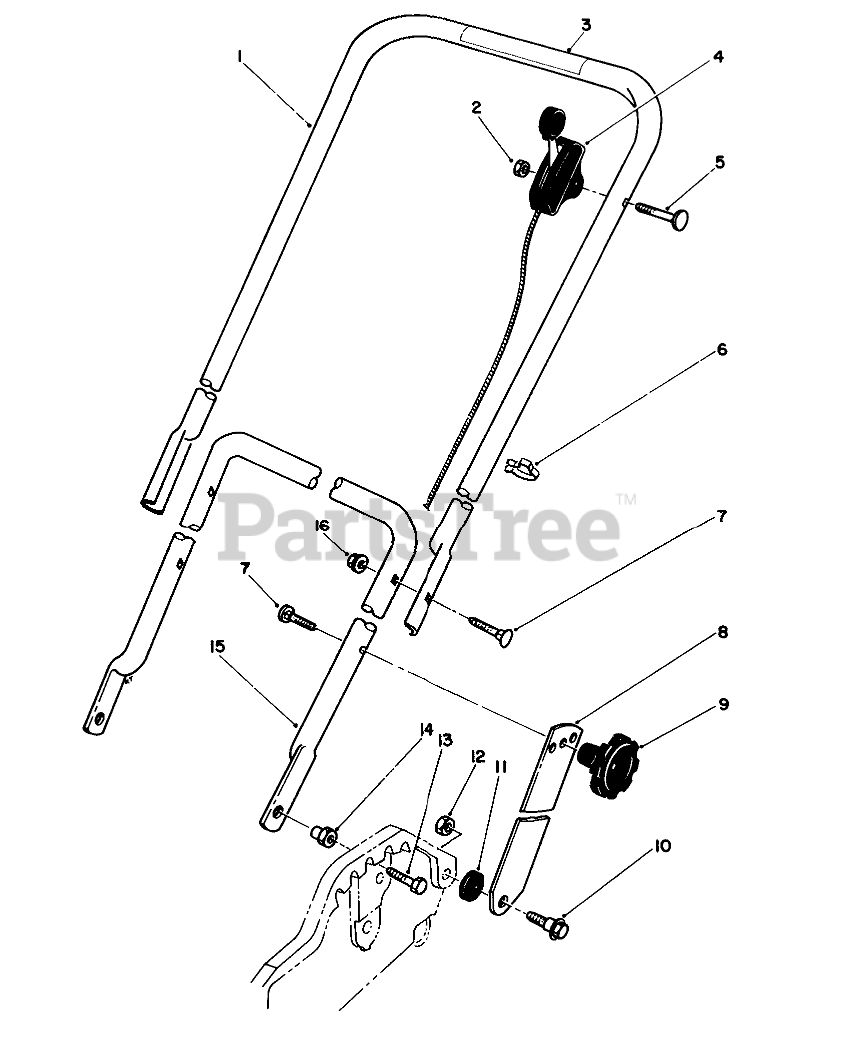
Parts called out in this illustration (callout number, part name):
1	Handle-Upper (Incl. Ref. #3)
1	HINGE PIN
2	NUT-LOCK, NI
2	BAG FRAME
3	Decal-Danger
3	NUT-PUSH
4	THROTTLE CONTROL
5	SCREW-HANDLE
5	BAG FRAME
6	BOWDEN CLIP
6	GRASS BAG DOOR
7	SCREW
7	SPRING
8	Handle Latch
10	SCREW-SHOULDER
11	SPACER
12	NUT-LOCK, NI
13	SCREW-HH
14	HANDLE PIVOT NUT
15	LOWER HANDLE
16	NUT-LOCK, NI
